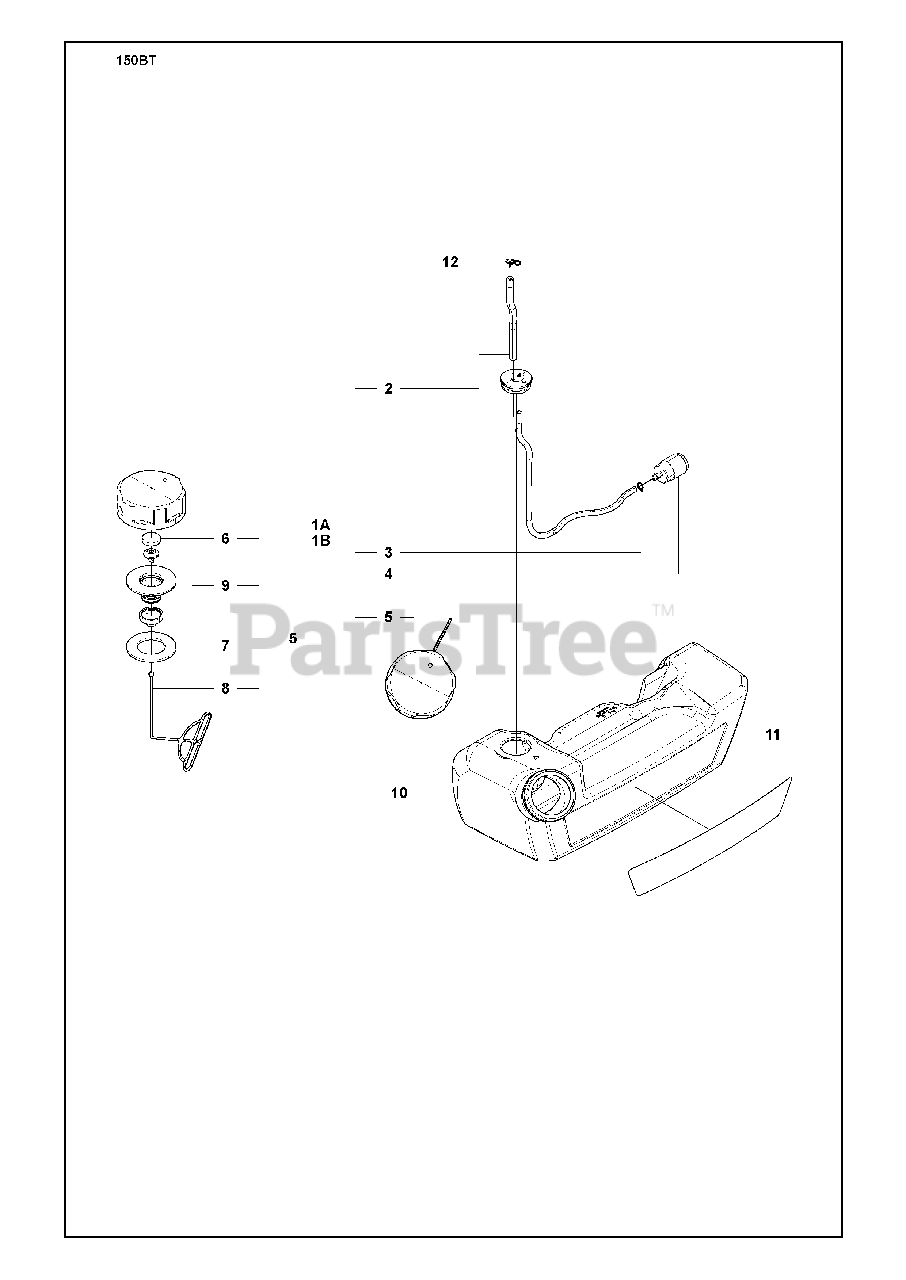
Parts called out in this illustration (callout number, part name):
1A	TANK ASSY
1B	TANK ASSY
2	PIPE C
3	CLIP
4	FILTER
5	ASSY FUEL CAP
6	FILTER
7	PACKING
9	HOLDER-A
12	CLIP
